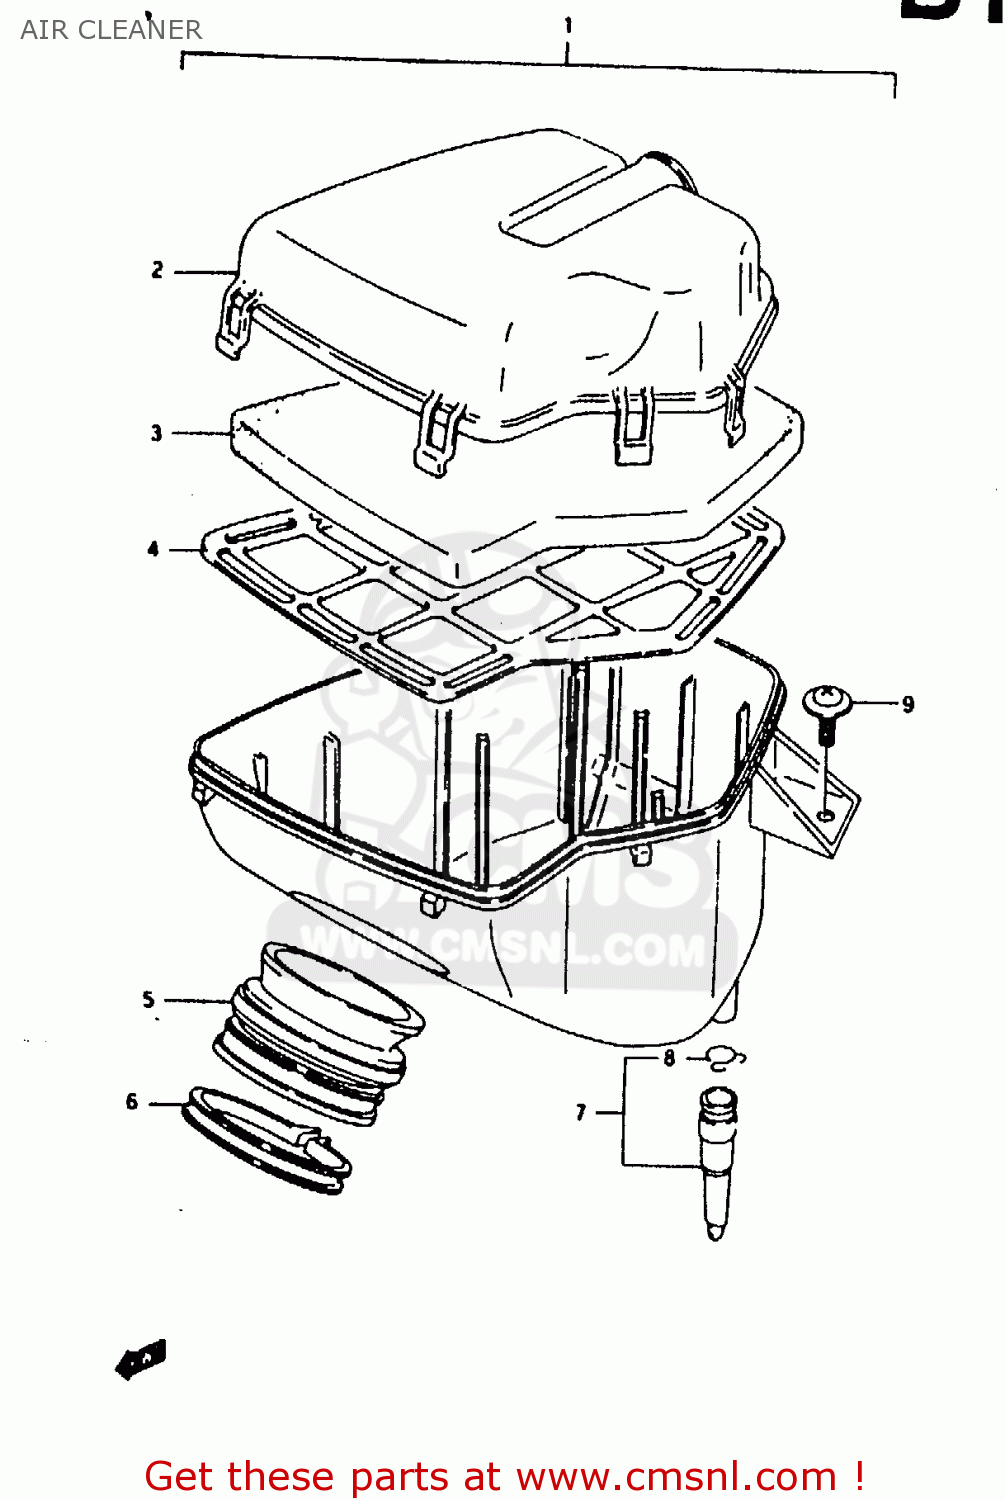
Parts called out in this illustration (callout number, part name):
1	CLEANER ASSY, AIR
2	CAP,AIR CLEANER
3	FILTER,AIR
4	HOLDER,FILTER
5	TUBE,OUTLET
6	CLAMP
7	CAP,DRAIN
8	CLIP
9	SCREW(6X16)
